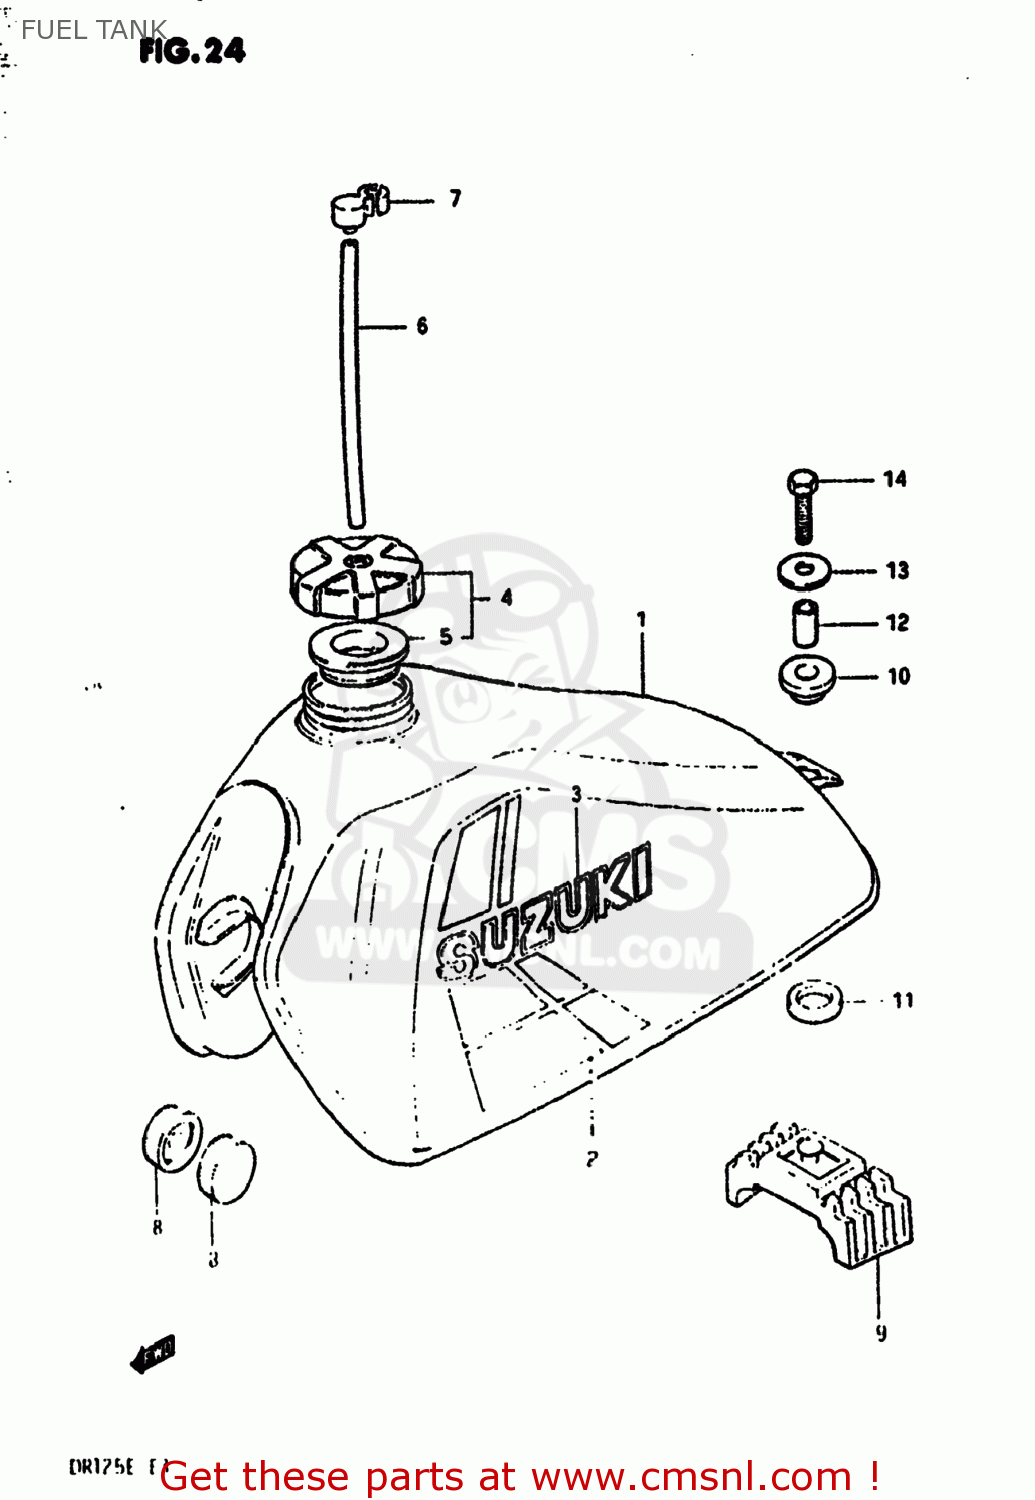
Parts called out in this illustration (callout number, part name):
1	TANK ASSEMBLY,FUEL
2	TAPE SET,FUEL TANK
3	EMBLEM
4	CAP SET,FUEL TANK
5	GASKET (NAS)
6	HOSE
7	CLAMP,FUEL TANK BREATHER HOSE
8	CUSHION
9	CUSHION,FUEL TANK
10	CUSHION
11	CUSHION
12	SPACER(8.5X12X19)
13	WASHER (8.5X29X1.6)
14	BOLT (8X30)
